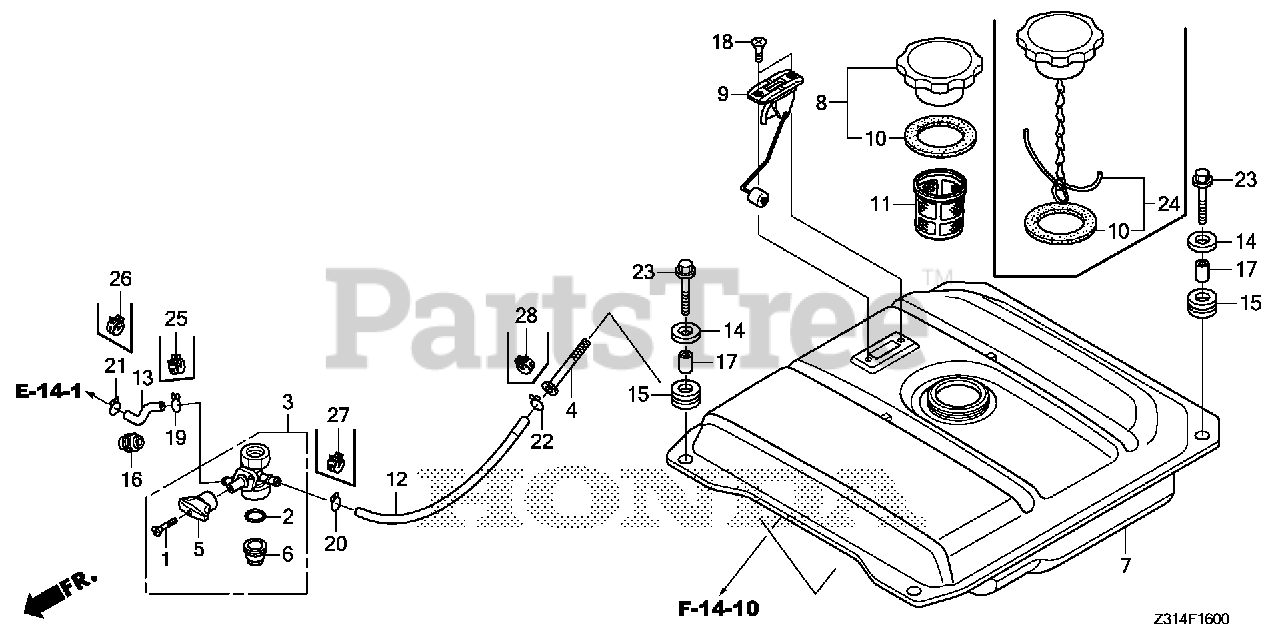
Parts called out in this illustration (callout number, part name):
1	SCREW, OVAL
2	GASKET, FUEL STRAINER CUP
3	PETCOCK ASSY.
4	FILTER, FUEL
5	LEVER, PETCOCK
6	CUP, FUEL STRAINER
7	TANK, FUEL *R280* (POWER RED)
9	METER ASSY., FUEL
10	GASKET, FUEL FILLER CAP
11	FILTER, FUEL
12	TUBE, FUEL TANK (FKM)
12	TUBE, FUEL TANK (FKM) (NOT AVAILABLE)
13	TUBE, FUEL (FKM)
13	TUBE, FUEL (FKM) (NOT AVAILABLE)
14	WASHER (6MM)
15	CUSHION, TANK RUBBER
16	RUBBER, FUEL (9X15X20)
17	COLLAR, TANK CUSHION
18	SCREW, FLAT (5X10)
23	BOLT, FLANGE (6X22)
24	CAP, FUEL FILLER
25	CLIP, TUBE (D8)
26	CLIP, TUBE (D8.5)
27	CLAMP, TUBE (D10)
28	CLAMP, TUBE (D12)
